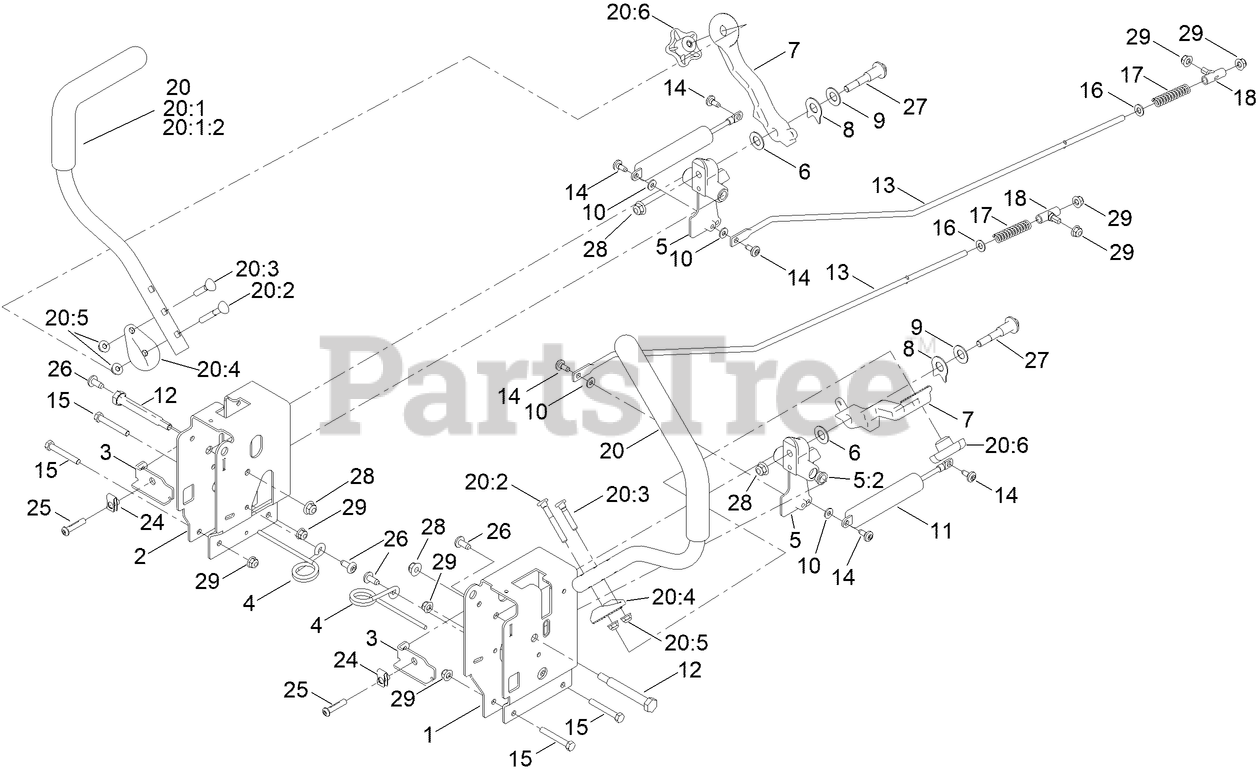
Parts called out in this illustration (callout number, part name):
1	CONTROL BOX - LH G7
2	CONTROL BOX - RH G7
3	ADJUSTMENT PLATE-CONTROL BOX
4	SPRING-TORSION
5	PIVOT ARM ASM
5:2	BUSHING-FLANGE
6	WASHER-NYLON
7	ARM-CONTROL, 32 TEETH
8	SPACER, ANTI-ROTATION
9	WASHER-BELLEVILLE
10	WASHER
11	DAMPER-NON CAVITATING
12	BOLT-PIVOT
13	ROD-HYDRO
14	SCREW-SHOULDER
15	SCREW-HH
16	WASHER-PLAIN
17	SPRING-COMPRESSION
18	MOUNT-ROD, HYDRO
20	HANDLE-CONTROL, ASM
20:1	HANDLE-CONTROL,
20:2	SCREW-HANDLE
20:3	SCREW-HANDLE
20:4	DISC-ADJUSTMENT HANDLE, 32 TEETH
20:5	NUT-HF
20:6	KNOB-HANDLE
25	SCREW-HSBH
27	BOLT-PIVOT
28	NUT-HF, NI
29	NUT-HF, NI
